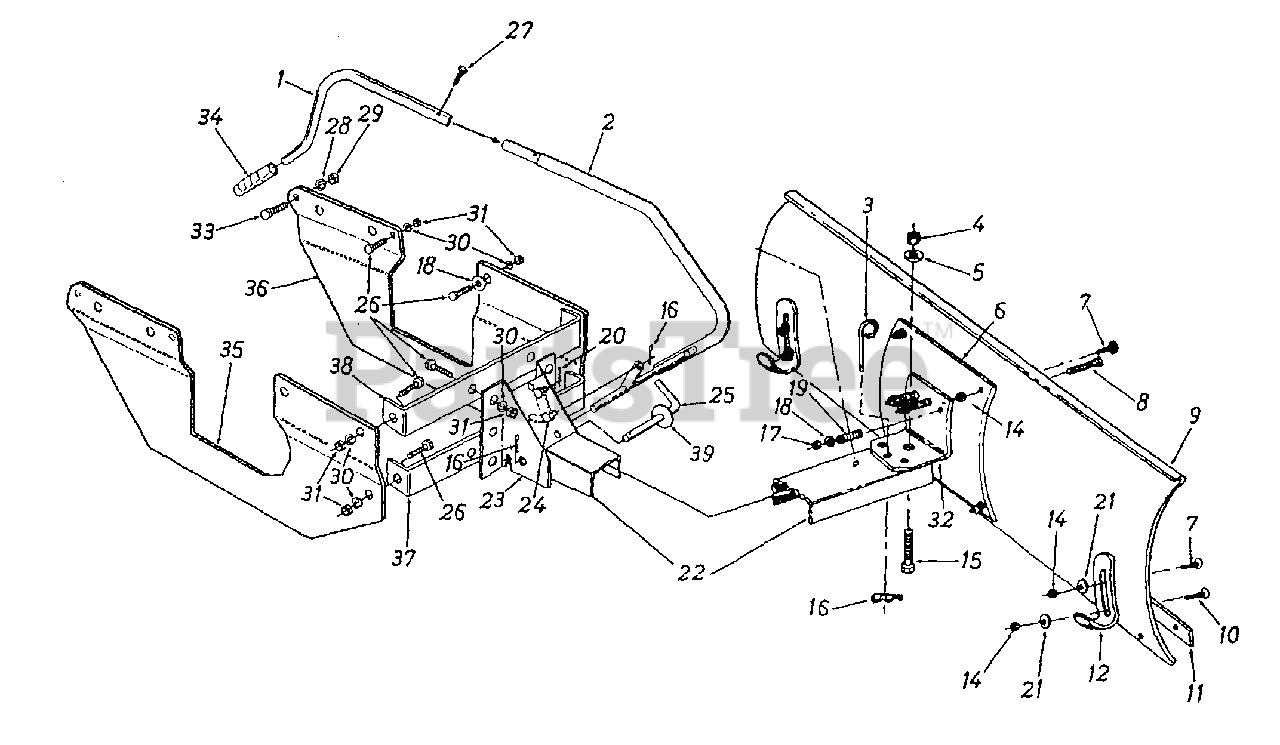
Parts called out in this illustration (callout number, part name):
1	Upper Lift Handle
2	Lift Handle Ass'y.
3	Pivot Lock Pin
4	Hex Cent. L-Nut 1/2-13 Thd.
5	Fl-Wash. 17/32" I.D.
6	Reinforcement Plate
7	Carriage Bolt 5/16-18 x .75" Lg.
8	Hex Bolt 3/8-16 x 4" Lg.
9	42" Blade
10	Carriage Bolt 5/16-18 x 1" Lg.
11	42" Wear Plate
12	Shoe Skid
14	Hex Cent. L-Nut 5/16-18 Thd.
15	Hex Bolt 1/2-13 x 1.25" Lg.
16	Int. Cotter Pin
17	Hex Cent. L-Nut 3/8-16 Thd.
18	Fl-Wash. 3/8" I.D.
19	Compression Spring
20	Cotter Pin 1/8" Dia, x 1" Lg.
21	Fl-Wash. 5/16" I.D.
22	Push Bar Channel
23	Pivot Support Bracket
24	Lift Link
25	Channel Pivot Shaft
26	Hex Bolt 3/8-16 x 1" Lg. Grade 5
27	Hex Bolt #10 x 5/8" Lg.
28	L-Wash. 1/4" I.D.
29	Hex Nut 1/4-20" Thd.
30	L-Wash. 3/8" I.D.
31	Hex Nut 3/8-16 Thd.
32	Support Bracket
33	Hex Bolt 1/4-20 x .75" Lg.
34	Rubber Grip
35	Frame Support Brkt. (R.H.)
36	Frame Support Brkt. (L.H.)
37	Support Brkt. (Lower)
38	Support Brkt. (Upper)
39	Fl-Wash. 17/32" I.D. x 1" O.D.
